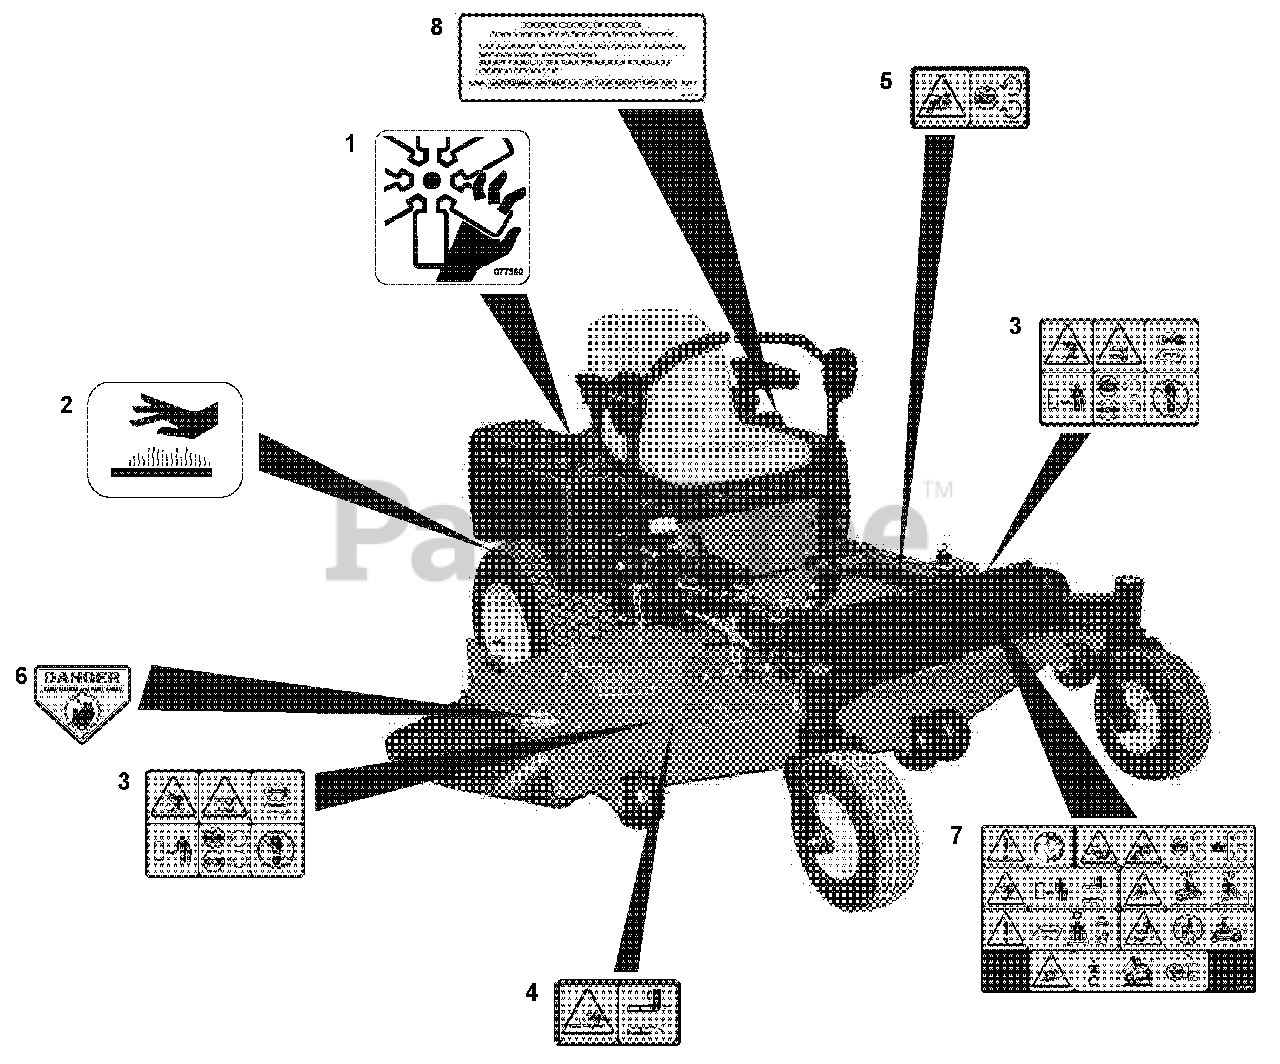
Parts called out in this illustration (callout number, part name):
1	DECAL, DANGER FAN
2	DECAL, HOT SURFACE
3	DECAL, SAFETY - MOWER DECK
4	DECAL, SAFETY - DECK GUARDING
5	DECAL, SAFETY - GUARDING
6	DECAL, DANGER
7	DECAL, MAIN SAFETY
8	LABEL, EPA NON-COMPLIANT TANK
